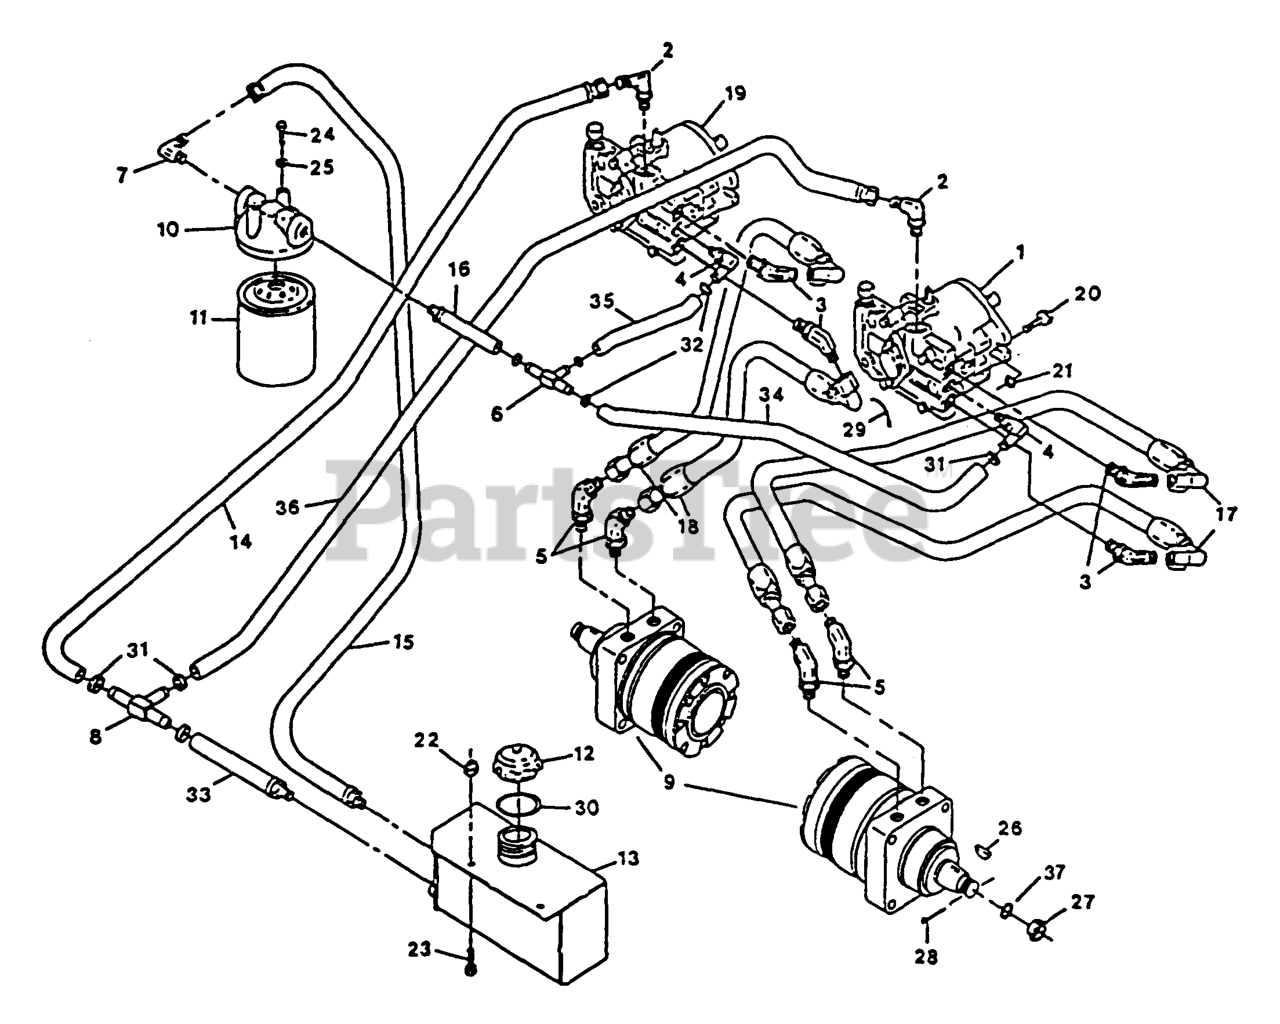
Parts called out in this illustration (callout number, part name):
2	FITTING-90 DEG
3	FITTING-HYD, 45 DEG
4	FITTING
5	FITTING-HYD, 45 DEG
6	FITTING-TEE, HOSE
8	FITTING-TEE, HOSE
9	MOTOR-WHEEL
10	FILTER-HEAD
14	LOW PRESSURE HOSE ASM
17	HOSE-PRESSURE, HIGH
18	HOSE,HIGH PRESSURE
25	WASHER-LOCK
28	PIN-COTTER
29	TIE-PLASTIC
30	GASKET-CAP, TANK
31	CLAMP-HOSE
32	CLAMP-HOSE
34	HOSE,LO PRESSURE
37	WASHER-SPACER
